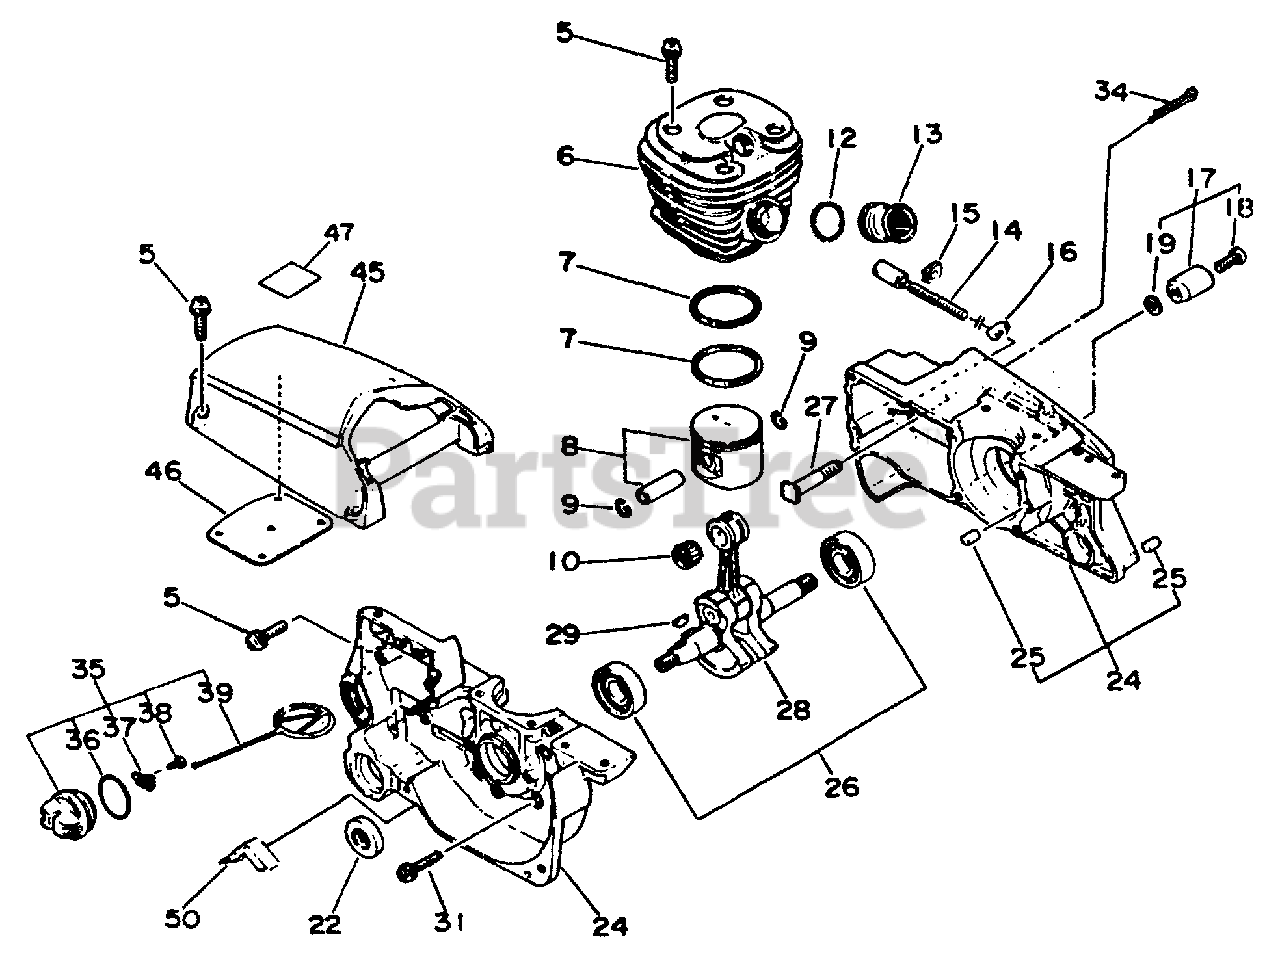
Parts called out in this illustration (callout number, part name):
5	SCREW - 5X20
6	CYLINDER
7	RING, PISTON
8	PISTON KIT
9	RING, RETAINING - 8
10	BEARING, NEEDLE - WHITE
10	BEARING, NEEDLE - BLUE
10	BEARING, NEEDLE - RED
12	BAND
13	BELLOWS, INTAKE
14	SCREW, TENSIONER
16	TENSIONER, CHAIN
17	CHAIN CATCHER KIT
18	SCREW - 5X20
19	WASHER - 5
22	SEAL, OIL
24	CRANKCASE KIT
25	PIN - LOCATING
26	BEARING SET
27	STUD, GUIDE BAR
28	CRANKSHAFT ASSY
31	SCREW - 5X30
34	PIN, SPLIT - 2X16
35	CAP ASSY
37	RETAINER
38	SCREW - 3X8
39	CONNECTOR, CAP
45	COVER, ENGINE
47	LABEL - KICK BACK
50	CUSHION
